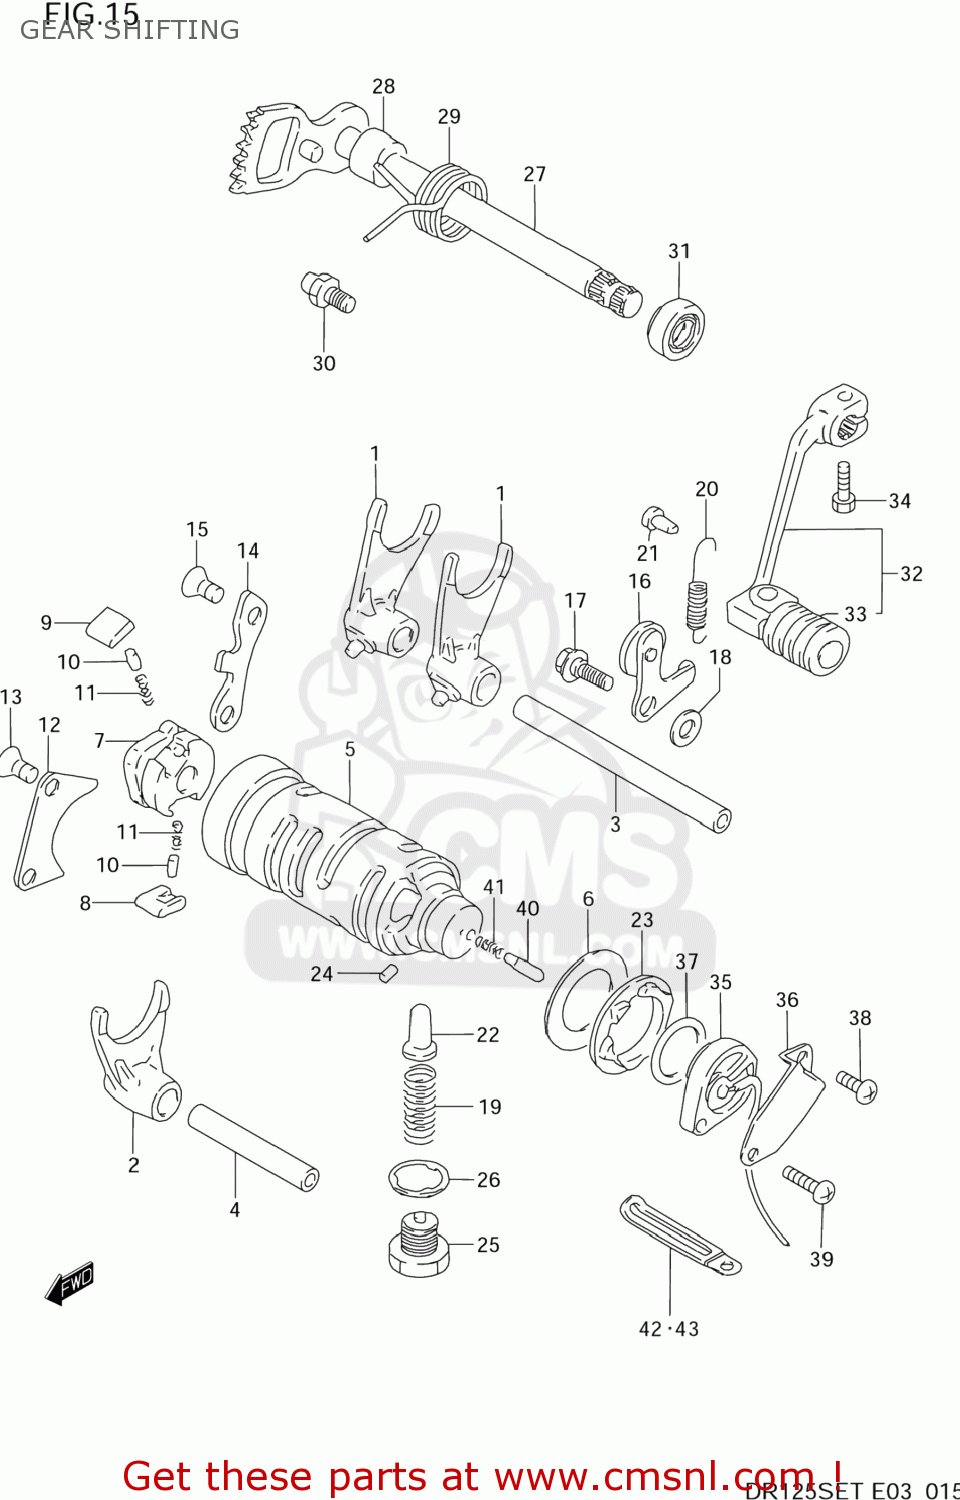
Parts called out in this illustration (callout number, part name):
1	FORK,GEAR SHIFT NO.2
2	FORK,GEAR SHIFT NO.3
3	SHAFT,GEAR SHIFT FORK
4	SHAFT,GEAR SHIFT FORK
5	CAM,GEAR SHIFT
6	WASHER,THRUST
7	GEAR,GEARSHIFT CAM DRIVE
8	PAWL,GEAR SHIFT NO.1
9	PAWL,GEAR SHIFT NO.2
10	PIN(5X8)
11	SPRING
12	LIFTER,GEAR SHIFT POLE
13	SCREW
14	GUIDE,GEAR SHIFT CAM
15	SCREW
16	STOPPER,GEAR SHIFT CAM
17	BOLT(6X14.6)
18	WASHER
19	SPRING
20	SPRING
21	RIVET
22	STOPPER,GEAR SHIFT CAM NO.2
23	PLATE,GEAR SHIFT CAM STOPPER
24	PIN
25	PLUG(14X12)
26	GASKET(13.8X18.8X4.8) (NAS)
27	SHAFT,GEAR SHIFT
28	SPACER(12X20X15.3)
29	SPRING
30	STOPPER,GEAR SHIFT CAM
31	OIL SEAL
32	LEVER ASSY,GEAR SHIFT
33	RUBBER,GEAR SHIFT PEDAL
34	BOLT
35	BASE ASSY,NEUTRAL SW TERMINAL
36	PROTECTOR,GEAR SHIFT SW
37	O RING(D:2.4,ID:21.8)
38	SCREW
39	SCREW
40	PIN(5X15.5)
41	SPRING
42	CLAMP
43	CLAMP
